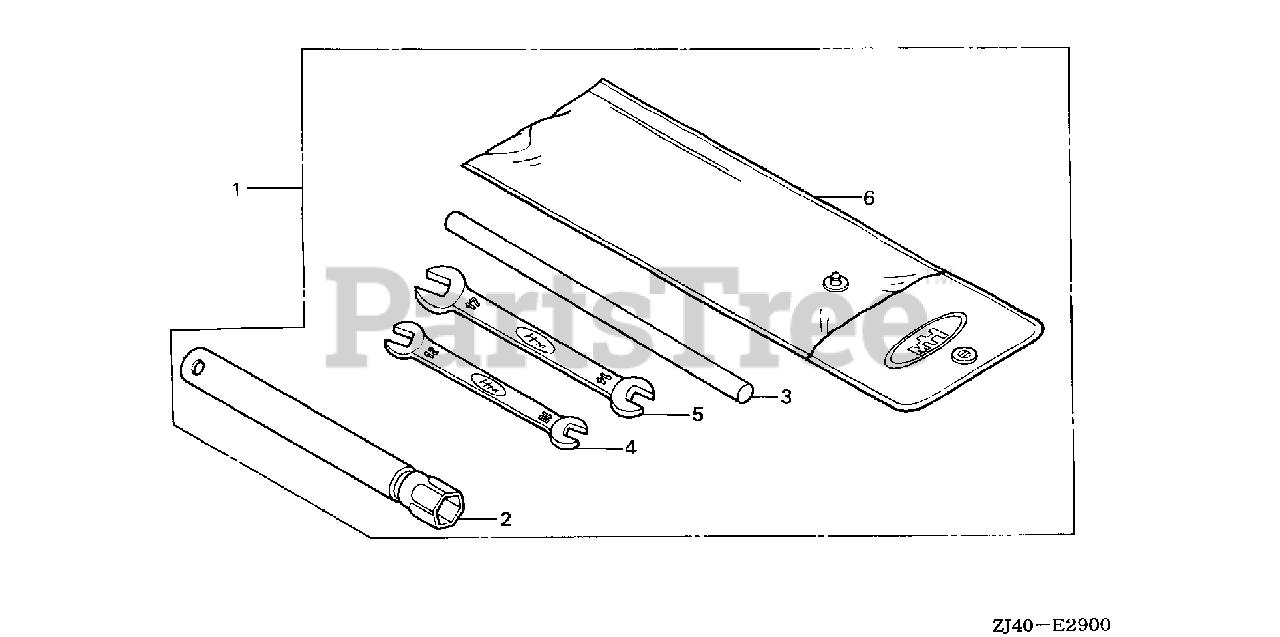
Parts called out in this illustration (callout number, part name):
1	TOOL KIT
2	WRENCH, SPARK PLUG
3	HANDLE, BOX WRENCH
4	SPANNER (10X12)
5	SPANNER (14X17)
6	BAG, TOOL (230MM)
